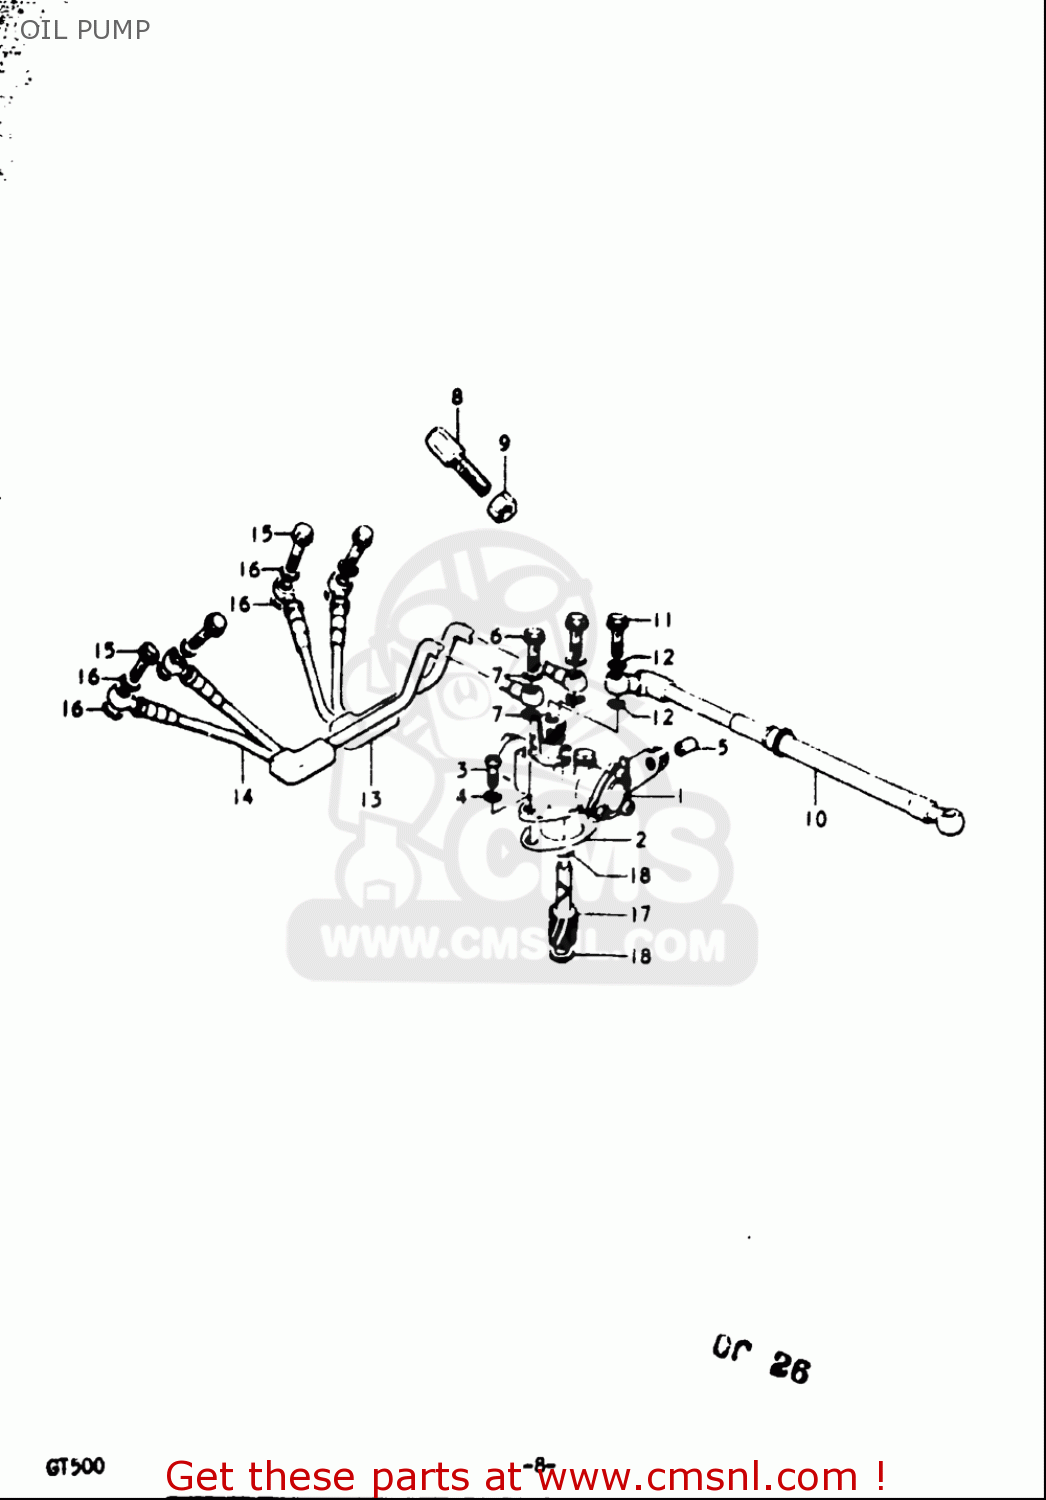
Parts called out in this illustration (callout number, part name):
3	SCREW
4	WASHER,LOCK
5	TERMINAL, CABLE
6	UNION
7	GASKET(6.2X11X1).2 (NAS)
8	BOLT
9	NUT
11	UNION BOLT
12	GASKET(6.2X11X1).2 (NAS)
15	UNION BOLT
16	GASKET(6.2X11X1).2 (NAS)
18	WASHER(8X13.7X1)
